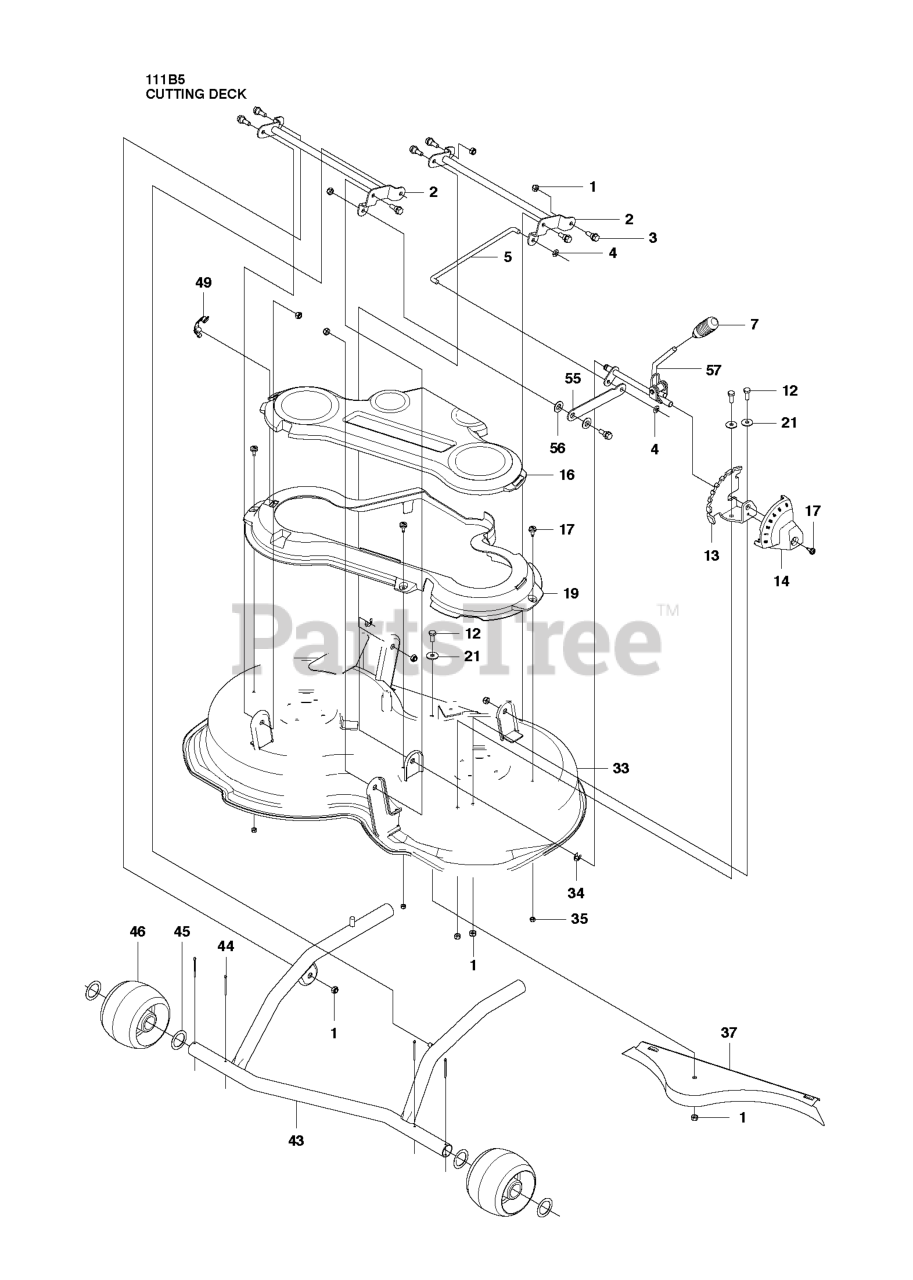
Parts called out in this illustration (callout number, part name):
1	LOCKNUT M8
21	WASHER
34	RETAINING RING
35	LOCKNUT M6
44	COTTER PIN
49	BUCKLE ORANGE
56	WASHER - 25X8.5X2.3
